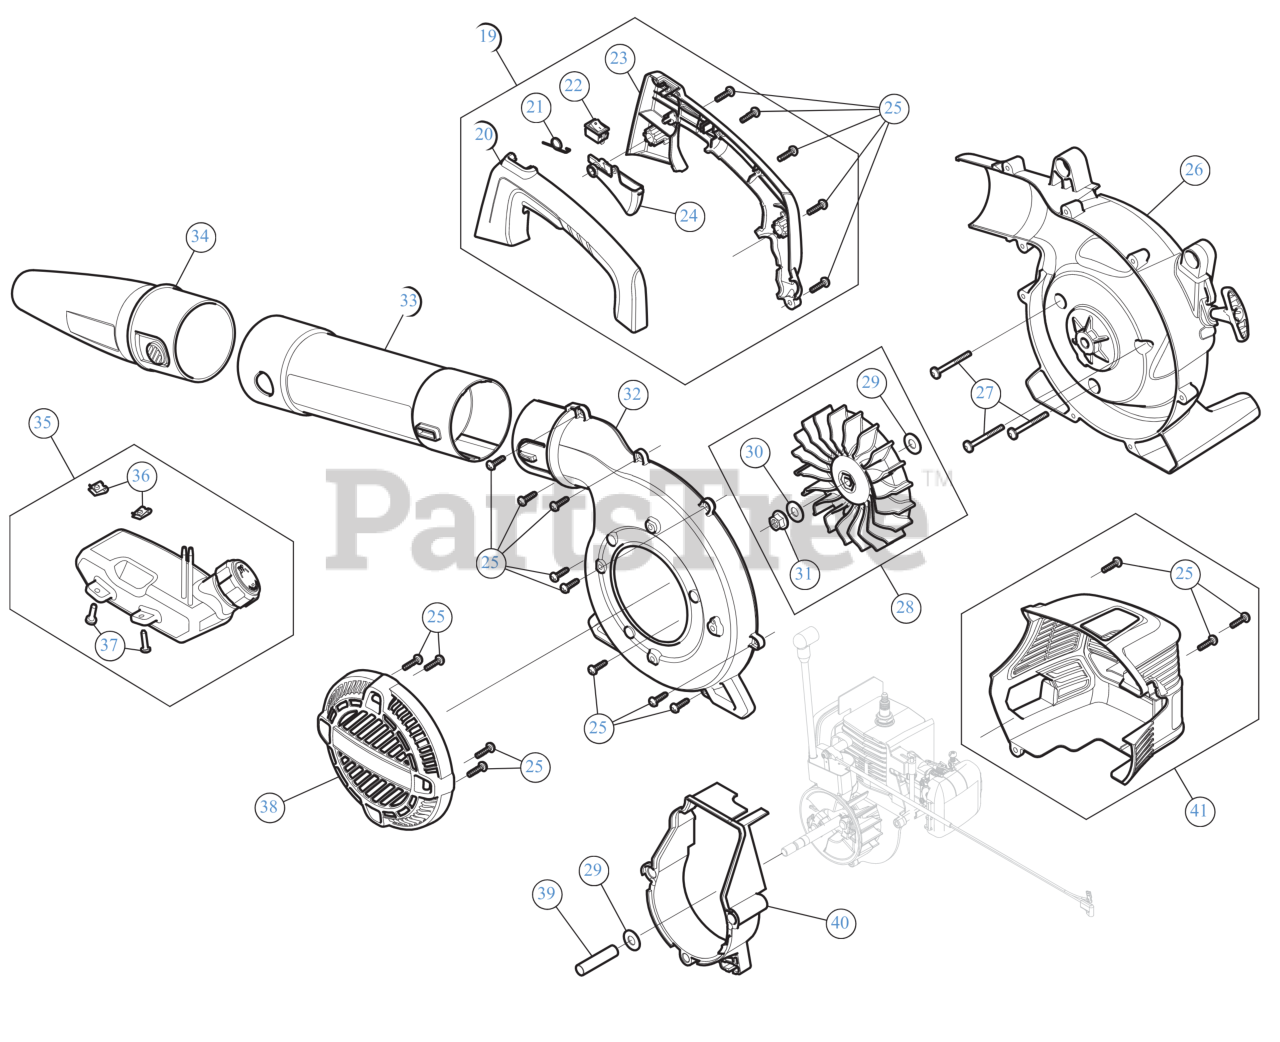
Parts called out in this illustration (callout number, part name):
19	HANDLE
20	HANDLE (LH)
21	TRIGGER SPRING
22	SW, MOMENTARY ON/O
23	HANDLE (RH)
24	THROTTLE TRIGGER
25	SCREW 8-16 x 3/4
26	IMPELLER HOUSING ASSEMBLY
27	SCREW 10/32
28	IMPELLER ASSEMBLY
29	FLAT WASHER
30	LOCK WASHER
31	NUT 3/8-24
32	IMPELLER HOUSING
33	TUBE UPPER
34	NOZZLE
35	FUEL TANK ASSEMBLY
36	NUT, TINNERMAN U-T
37	SCREW:10-6 x .75
38	INTAKE COVER
39	SPACER
40	ENGINE ADAPTER
41	ENGINE COVER
